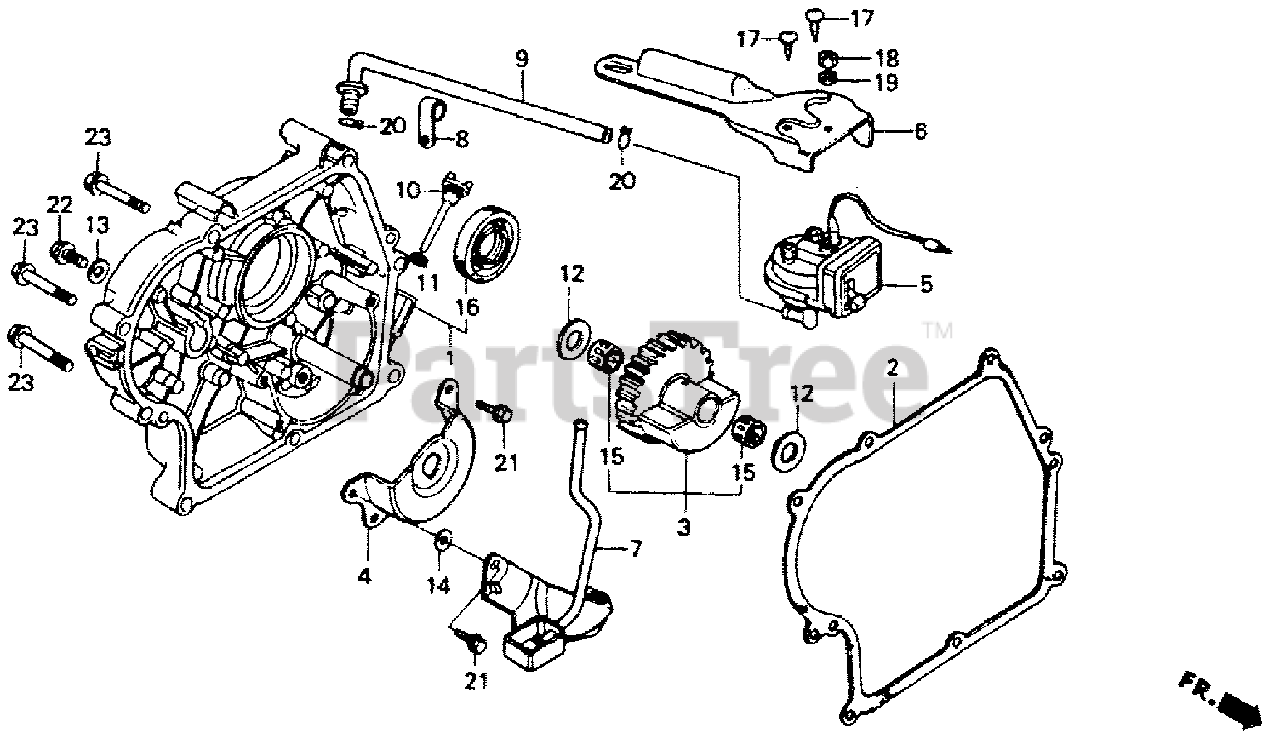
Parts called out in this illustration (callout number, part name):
1	COVER ASSY., CRANKCASE (QZ-TYPE)
2	GASKET, CASE COVER
3	WEIGHT, BALANCER
4	COVER, BALANCER
5	SWITCH ASSY., UNIT
6	BRACKET, UNIT SWITCH
7	CUP, OIL
8	CLAMP, TUBE
9	TUBE, OIL ALERT
10	CAP, OIL FILLER
11	GASKET, OIL FILLER CAP
12	WASHER, THRUST (15MM)
13	WASHER A (8MM)
14	WASHER, CRANK ARM
15	BEARING, NEEDLE
16	OIL SEAL (30X46X8)
17	SCREW, TAPPING (5X10)
18	NUT, HEX. (5MM)
19	WASHER, SPRING (5MM)
20	CLIP, TUBE (C11)
21	BOLT, FLANGE (6X16)
22	BOLT, FLANGE (8X12)
23	BOLT, FLANGE (8X45)
